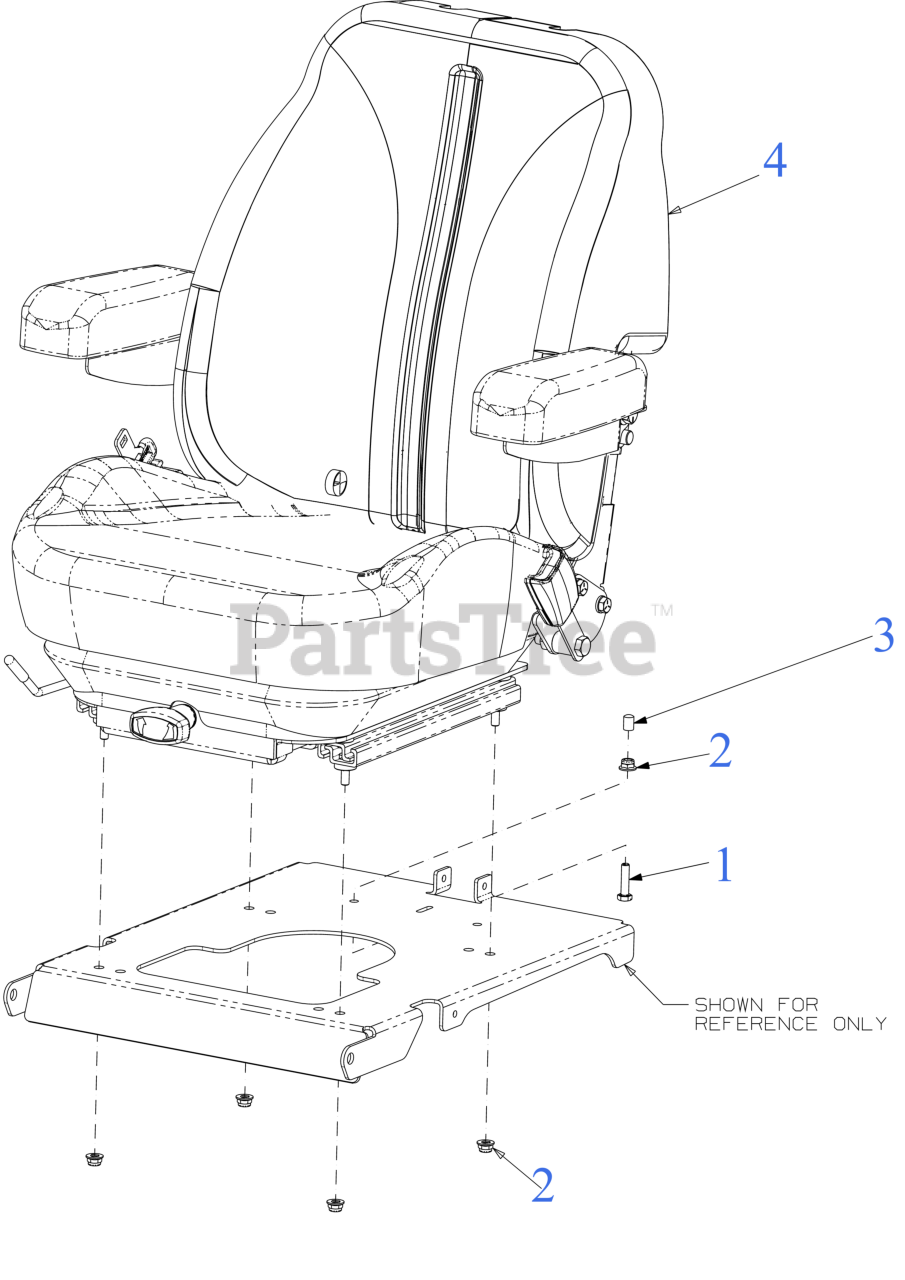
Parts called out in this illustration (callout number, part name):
1	SCREW 5/16-18 x 1.25 GR5
2	FLANGE LOCK NUT 5/16-18
4	SEAT (CUB SLIDE/SUSP/BELT/ARM)
4	SEAT SWITCH N/C,N/C
